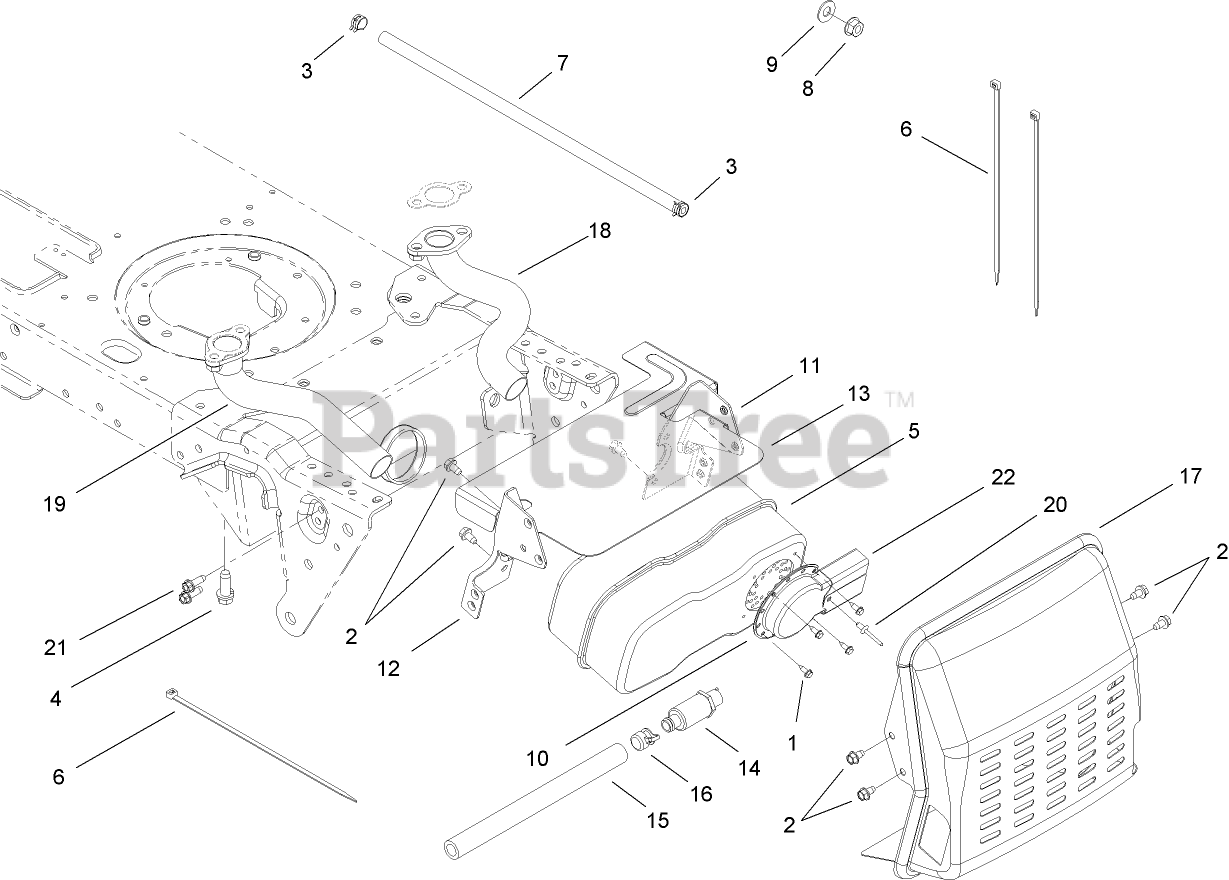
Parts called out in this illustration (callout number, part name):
1	SCREW-HWHTF
2	SCREW-HWHTF
3	CLAMP-HOSE
4	SCREW-TAP
5	MUFFLER-INLET, DUAL
6	TIE-CABLE
7	HOSE-FUEL
8	NUT-LOCK, FLANGE
9	WASHER-FLAT
10	DEFLECTOR-MUFFLER
11	BRACKET-MUFFLER, LH
12	BRACKET-MUFFLER, RH
13	SHIELD-HEAT
15	HOSE-DRAIN
17	MUFFLER SHIELD ASM
18	PIPE-EXHAUST, LH
19	PIPE-EXHAUST, RH
20	RIVET-POP
21	SCREW-TAP
22	DEFLECTOR-MUFFLER, LONG
